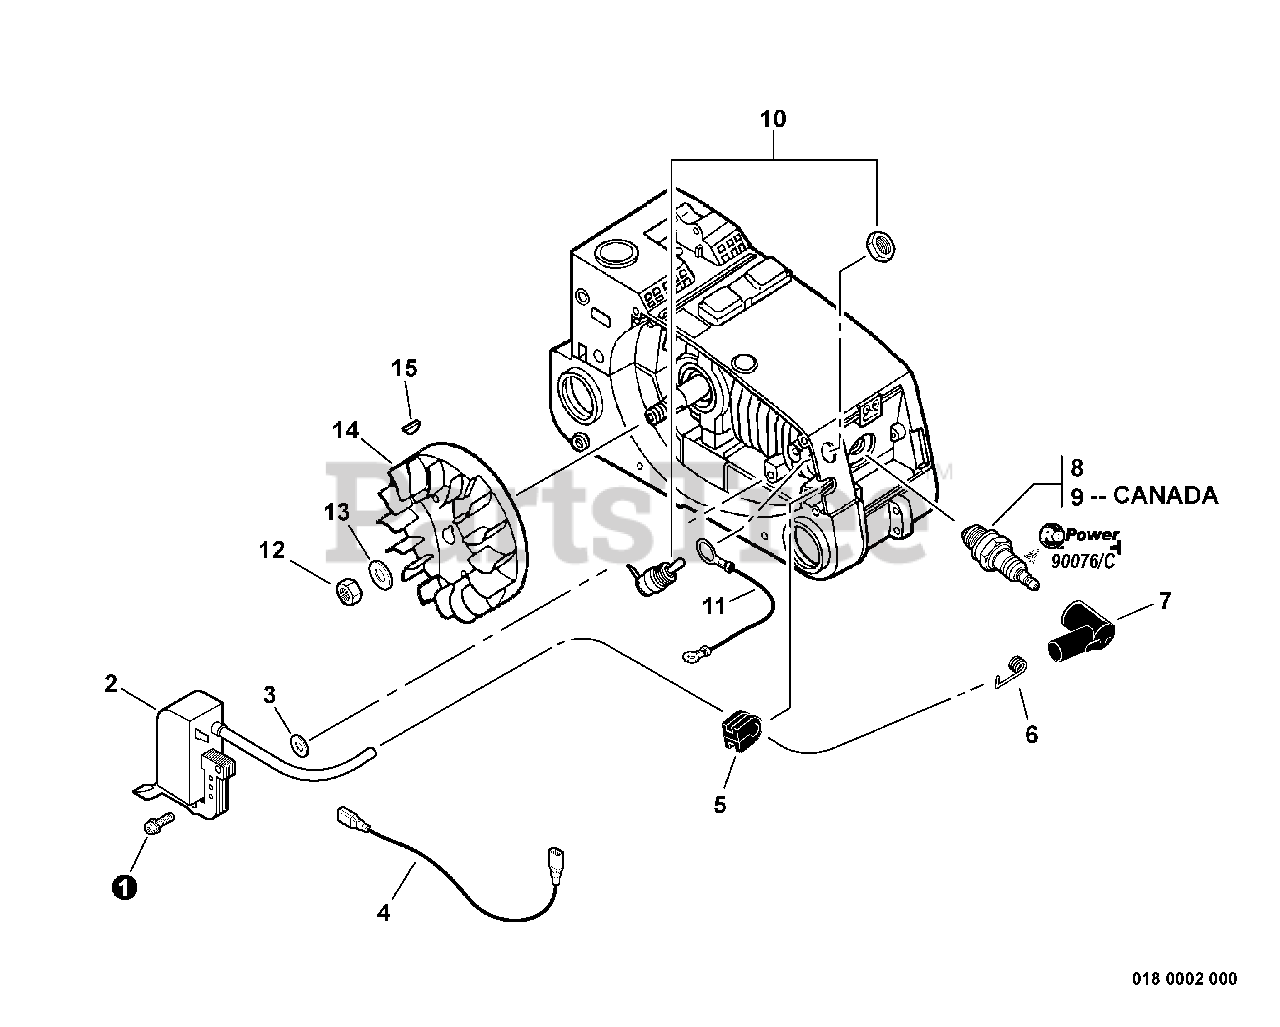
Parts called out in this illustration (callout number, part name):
1	SCREW - 5X22
2	COIL, IGNITION
4	LEAD - IGNITION
6	TERMINAL, SPARK PLUG CAP
7	CAP, SPARK PLUG
8	SPARK PLUG -- BPM-8Y
9	SPARK PLUG -- BPMR-8Y
10	IGNITION SWITCH KIT
11	LEAD - GROUND
13	WASHER - 8
14	FLYWHEEL
16	RePower TUNE-UP KIT
